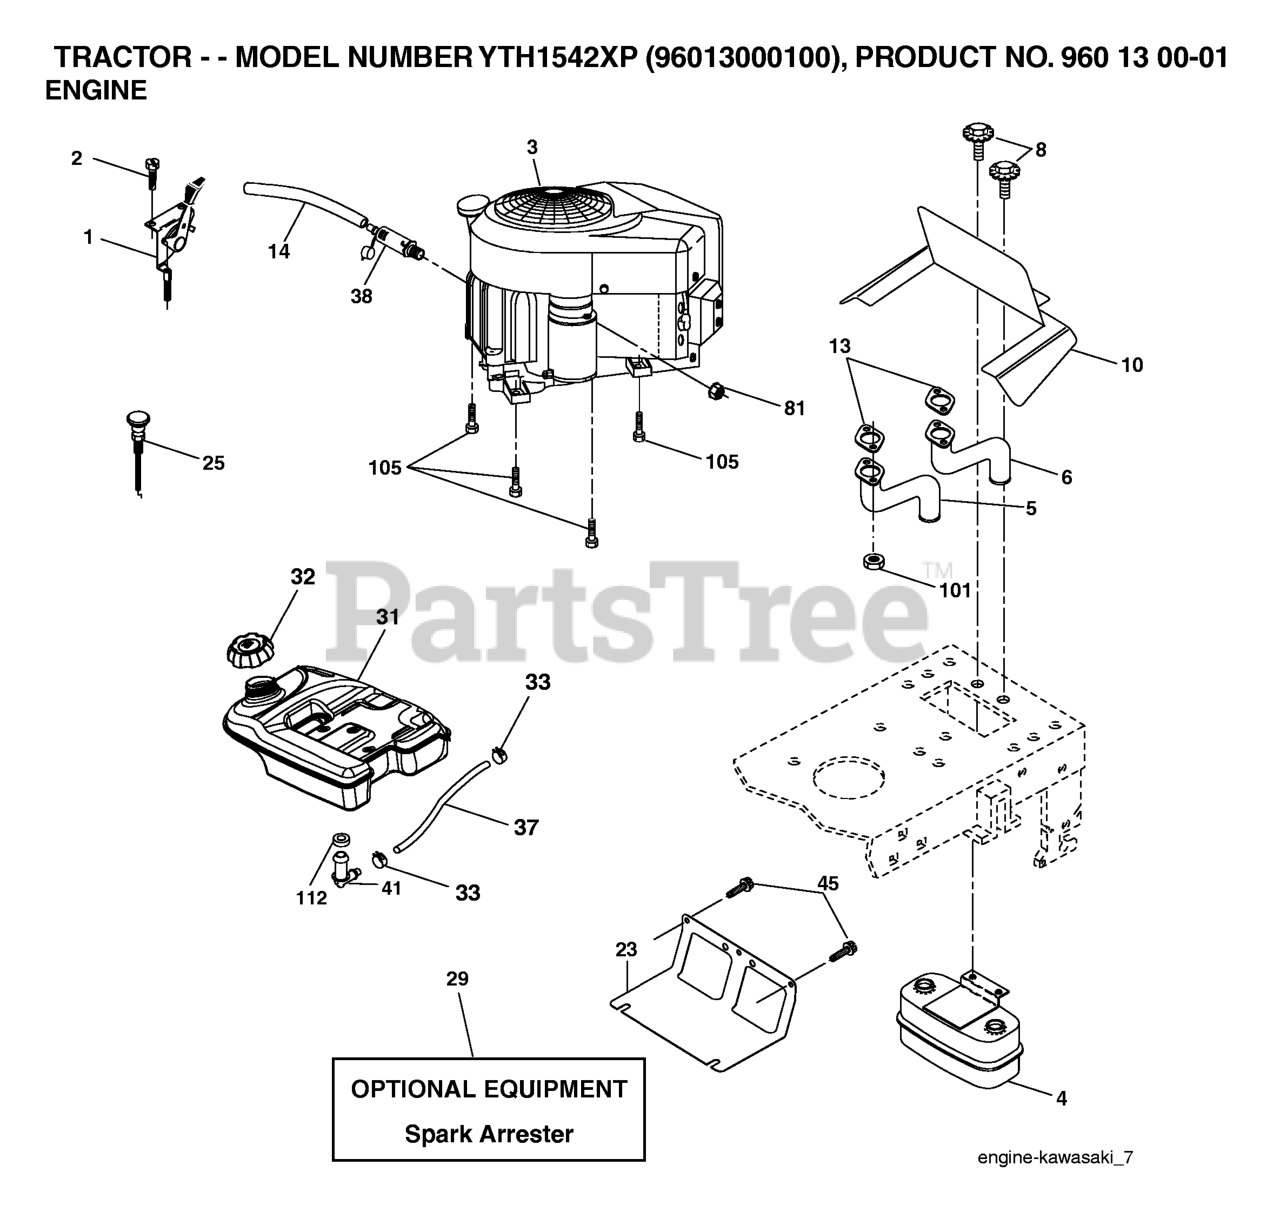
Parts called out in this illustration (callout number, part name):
1	CONTROL, THROTTLE
2	SCREW
4	MUFFLER.TWIN.CYL.LOW.TONE
5	EXHAUST TUBE LH KAWI
6	EXHAUST TUBE RH KAWI
8	BOLT.5/16-18UNCX3/4 W/SEMS.BLK
10	RP SHIELD HEAT MUFFLER
14	TUBE, DRAIN OIL ASM.
23	SHIELD.BROWNING.DBR.GUARD
25	CONTROL THROTTLE
29	KIT.SPARK ARRESTOR 794945 B&S
31	4.0 REAR FUEL TANK
32	TANK CAP
33	HOSE CLAMP
37	BRACKET ASM.SHIFT.CRT
41	STEM FUEL TANK
45	SCREW, 3/8-16X3/4
81	NUT
101	NUT.HEX.FLANGE.TOPLOCK
105	SCREW 3/8-16X1
112	BUSHING OUTLET T
